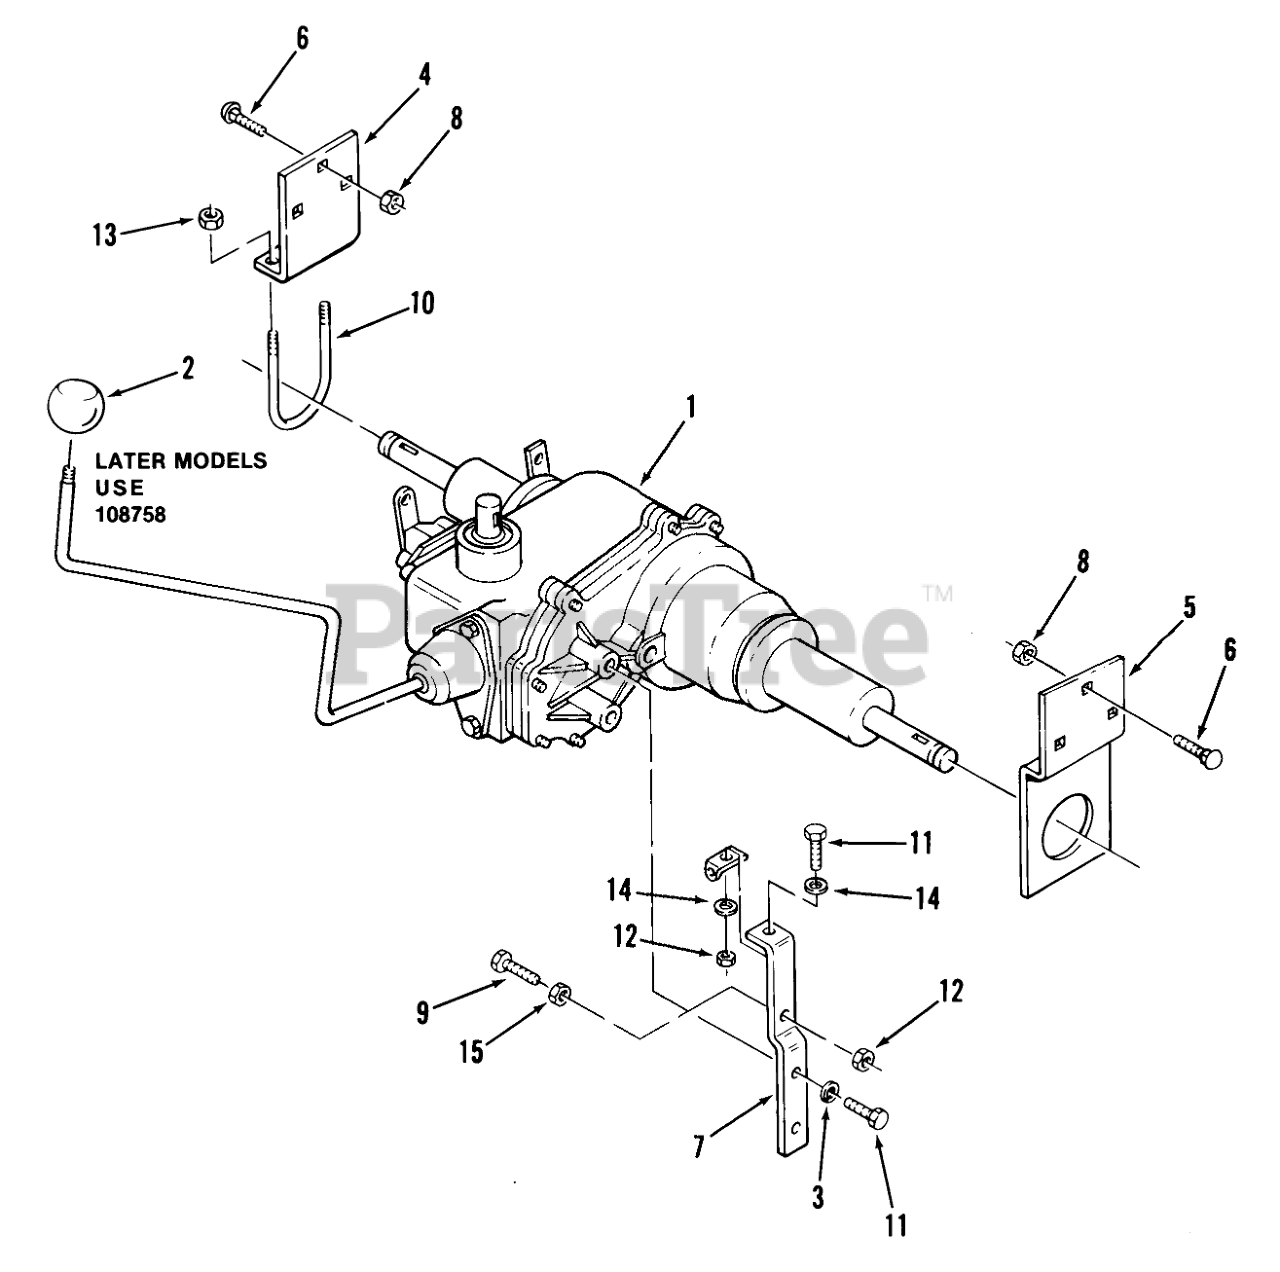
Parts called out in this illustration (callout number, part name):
1	Transmission-Peerless Mod. 601-001
2	SHIFT KNOB
3	Lockwasher
4	BRACKET-AXLE RH
5	BRACKET-AXLE LH
6	CARRIAGE BOLT -4
7	Bracket Trans. Mounting
8	Nut
9	Bolt 5/16-18 x 2
10	"U" Bolt Axle Mount
11	Bolt
12	Nut
13	Nut
14	WASHER 5/16 SAE
15	Jam Nut 5/16-18
